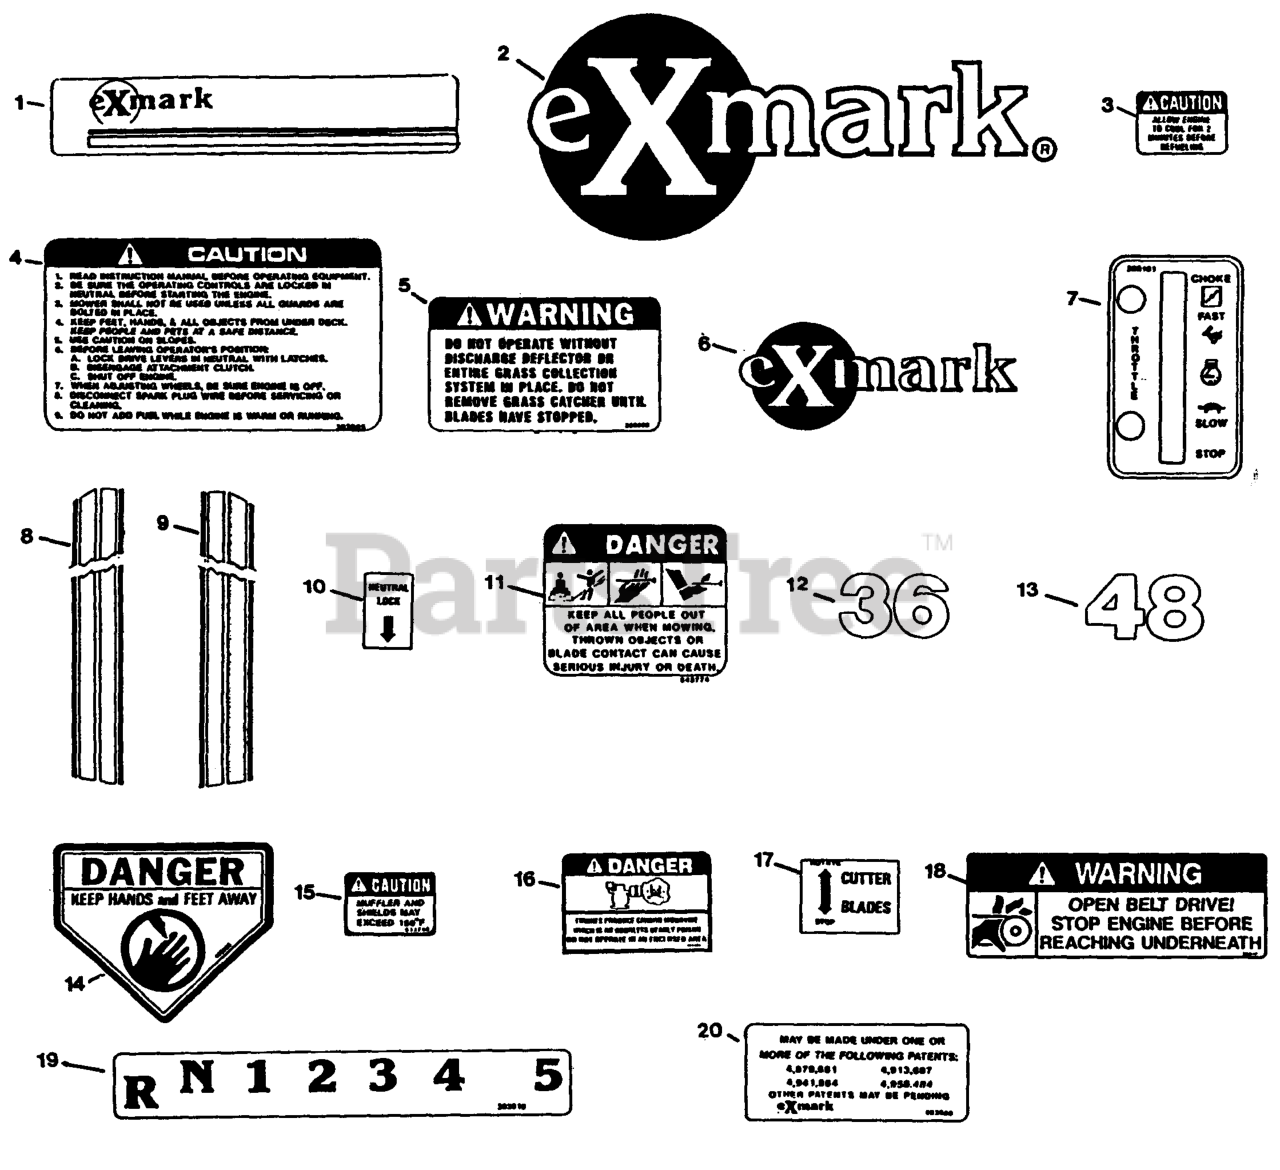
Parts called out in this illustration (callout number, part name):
4	LABEL,INSTRUCTION
5	DECAL-WARNING, DISCHARGE
10	DECAL,NEUTRAL LOCK
11	DECAL-DANGER
14	DECAL-DANGER
17	DECAL,CUTTER BLADE
18	DECAL,BELT DRIVE
19	DECAL,SHIFTER
